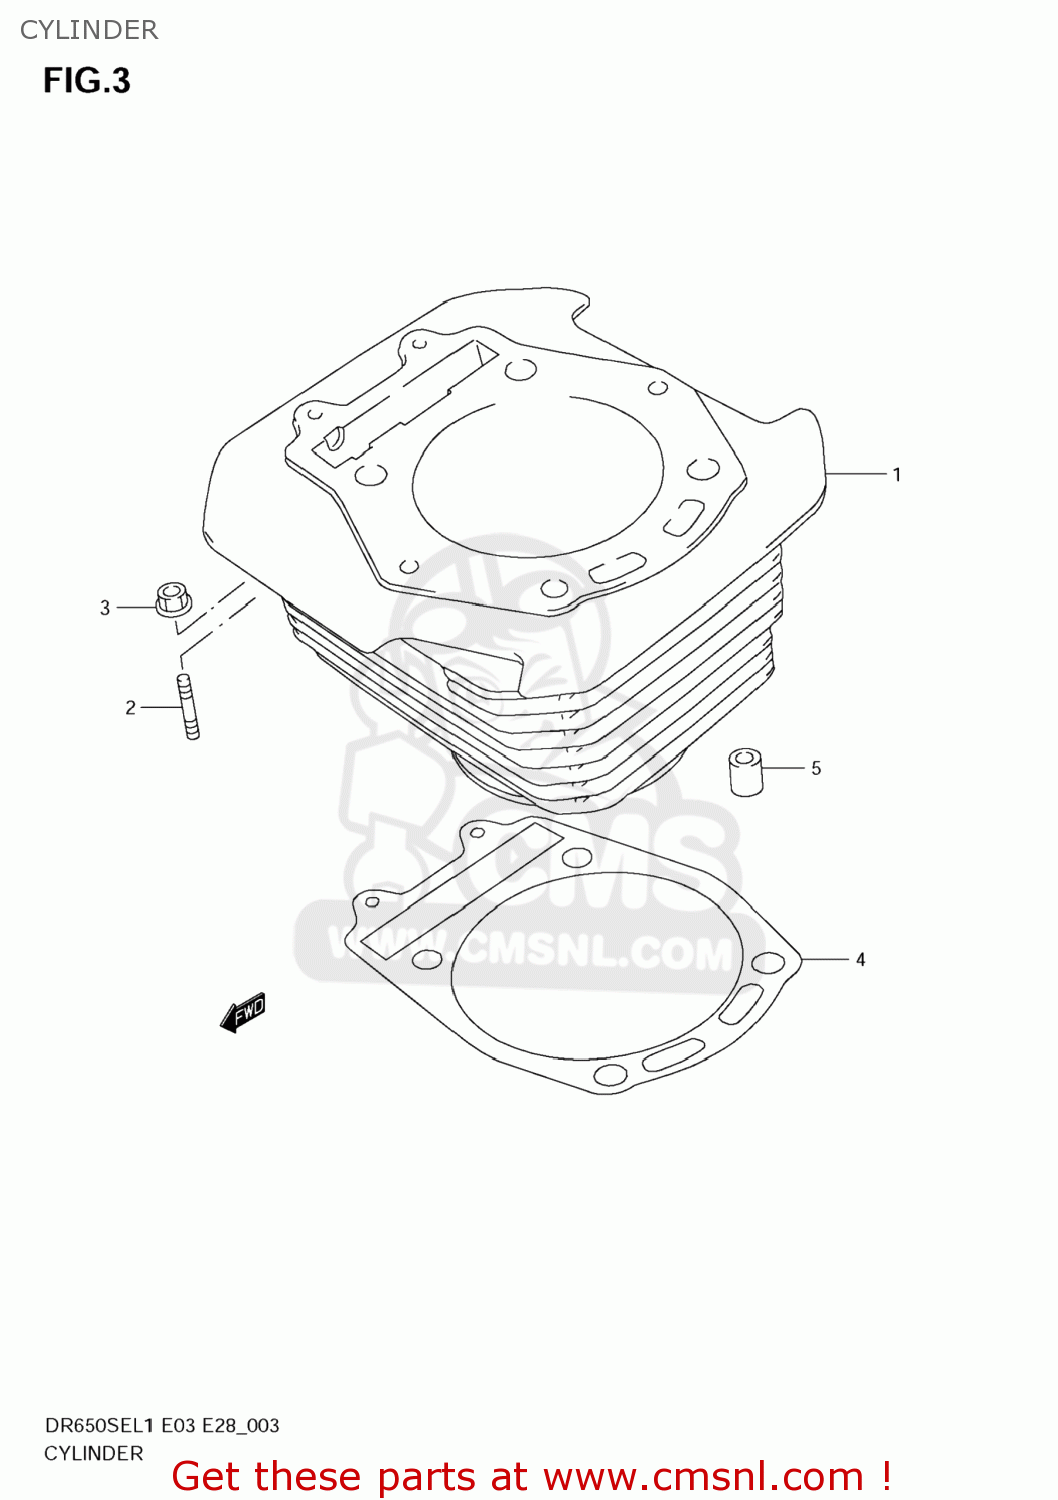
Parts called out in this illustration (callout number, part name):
1	CYLINDER
2	BOLT,STUD
3	NUT
4	GASKET,CYLINDER (NAS)
5	PIN
